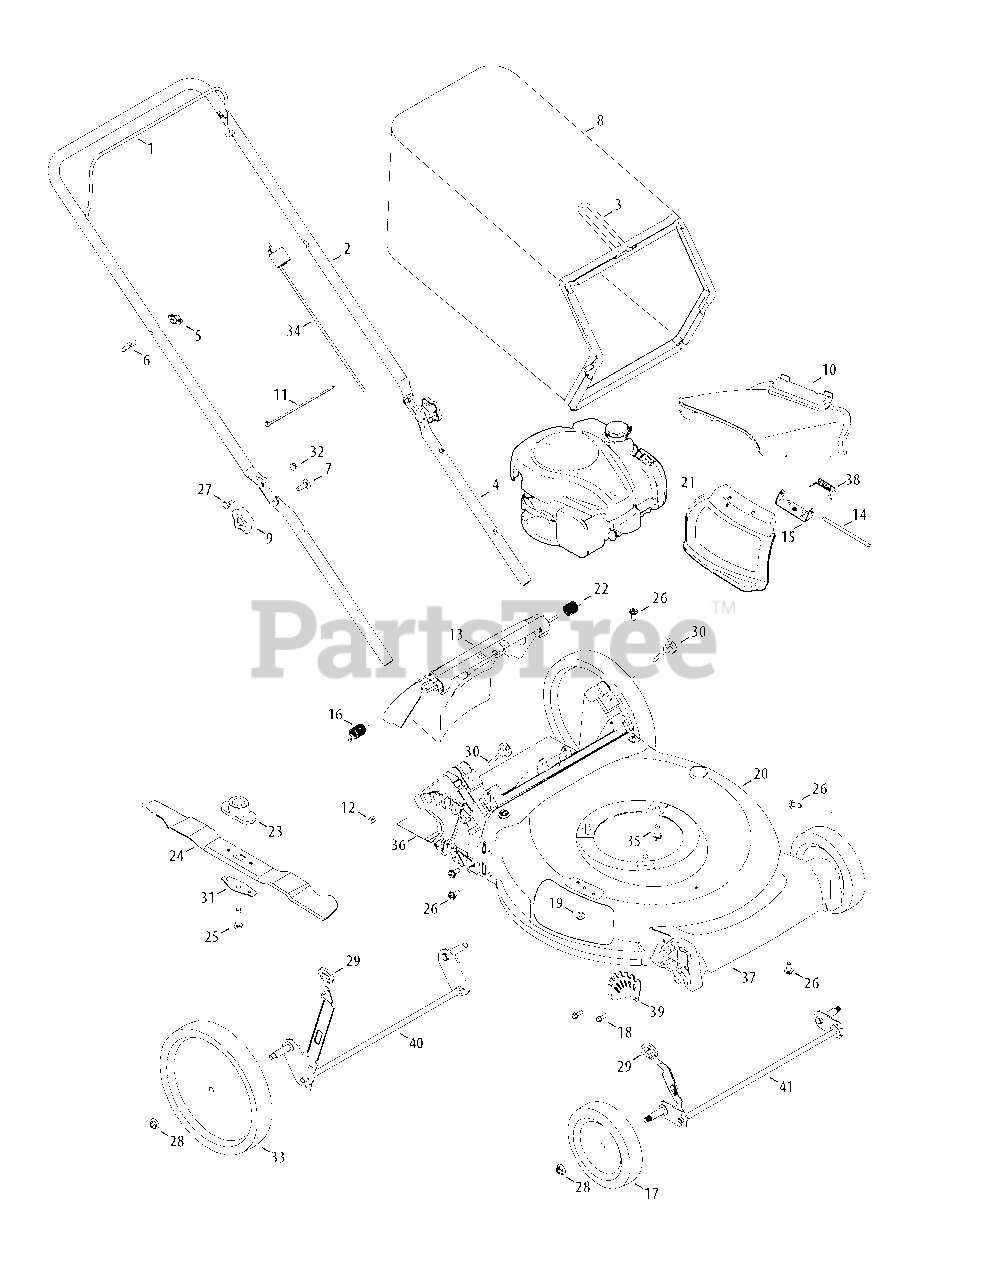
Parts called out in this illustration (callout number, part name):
1	Blade Control
2	Upper Handle
4	Lower Handle
5	Wing Nut
6	Rope Guide
7	Carriage Screw, 5/16-18
8	Grass Bag
9	Hand Knob
10	Side Chute
11	Cable Tie
12	Nut, Sq., 1/4-20
13	Rear Discharge Door Assembly
14	Hinge Pin
15	Chute Deflector Bracket
16	Torsion Spring - RH
17	Wheel, 7" x 1.8"
18	Screw, 1/4-15 x .750
19	Screw, 1/4-20 x .500
20	Deck - 21"
21	Hinged Mulch Plug Assembly
22	Torsion Spring - LH
23	Blade Adapter
24	Mulching Blade
25	Screw , 3/8-24 x 1.50
26	Screw, 5/16-14 x .750
27	Sldr. Screw, .375 x .126 x 1/4-20
28	Flange Lock Nut, 3/8-16
29	Adjustment Lever Knob
30	Wing Nut
31	Blade Bell Support
32	Nut, Flange Lock, 1/4-20
33	Wheel, 11" x 1.75"
34	Control Cable
35	TT Screw, 3/8-16 x 1.0
36	Trail shield
37	Front Cover
38	Torsion Spring
39	Front Height Adjuster Plate
40	Rear Axle Assembly
41	Front Axle Assembly
